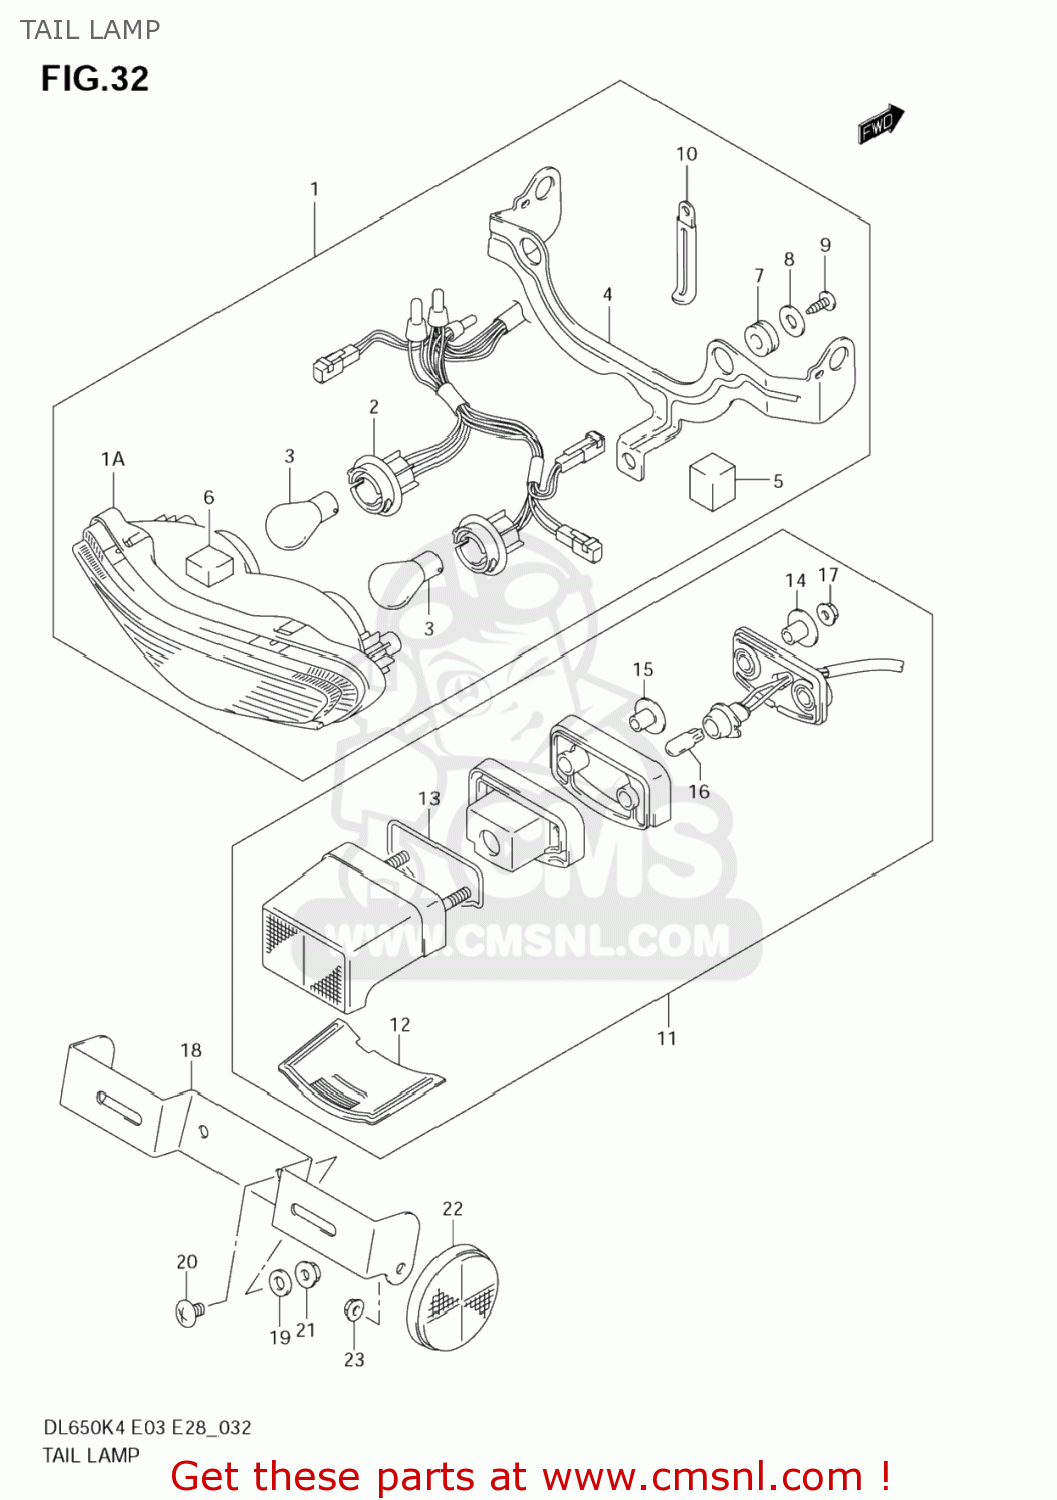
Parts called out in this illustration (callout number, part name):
1	LAMP ASSY,RR COMBINATION
1A	UNIT
2	SOCKET & CORD
3	BULB(12V21/5W)
4	BRACKET
5	CUSHION
6	CUSHION
7	CUSHION
8	WASHER(5.5X20X1.2)
9	SCREW
10	CLAMP(L:65)
11	LAMP ASSY,LICENSE
12	LENS
13	GASKET (NAS)
14	SPACER
15	SPACER
16	BULB(12V5W)
17	NUT
18	BRACKET,LICENSE PLATE
19	WASHER(6.5X15X1.6)
20	SCREW 6X12
21	NUT
22	REFLECTOR ASSY,RR SIDE
23	NUT
